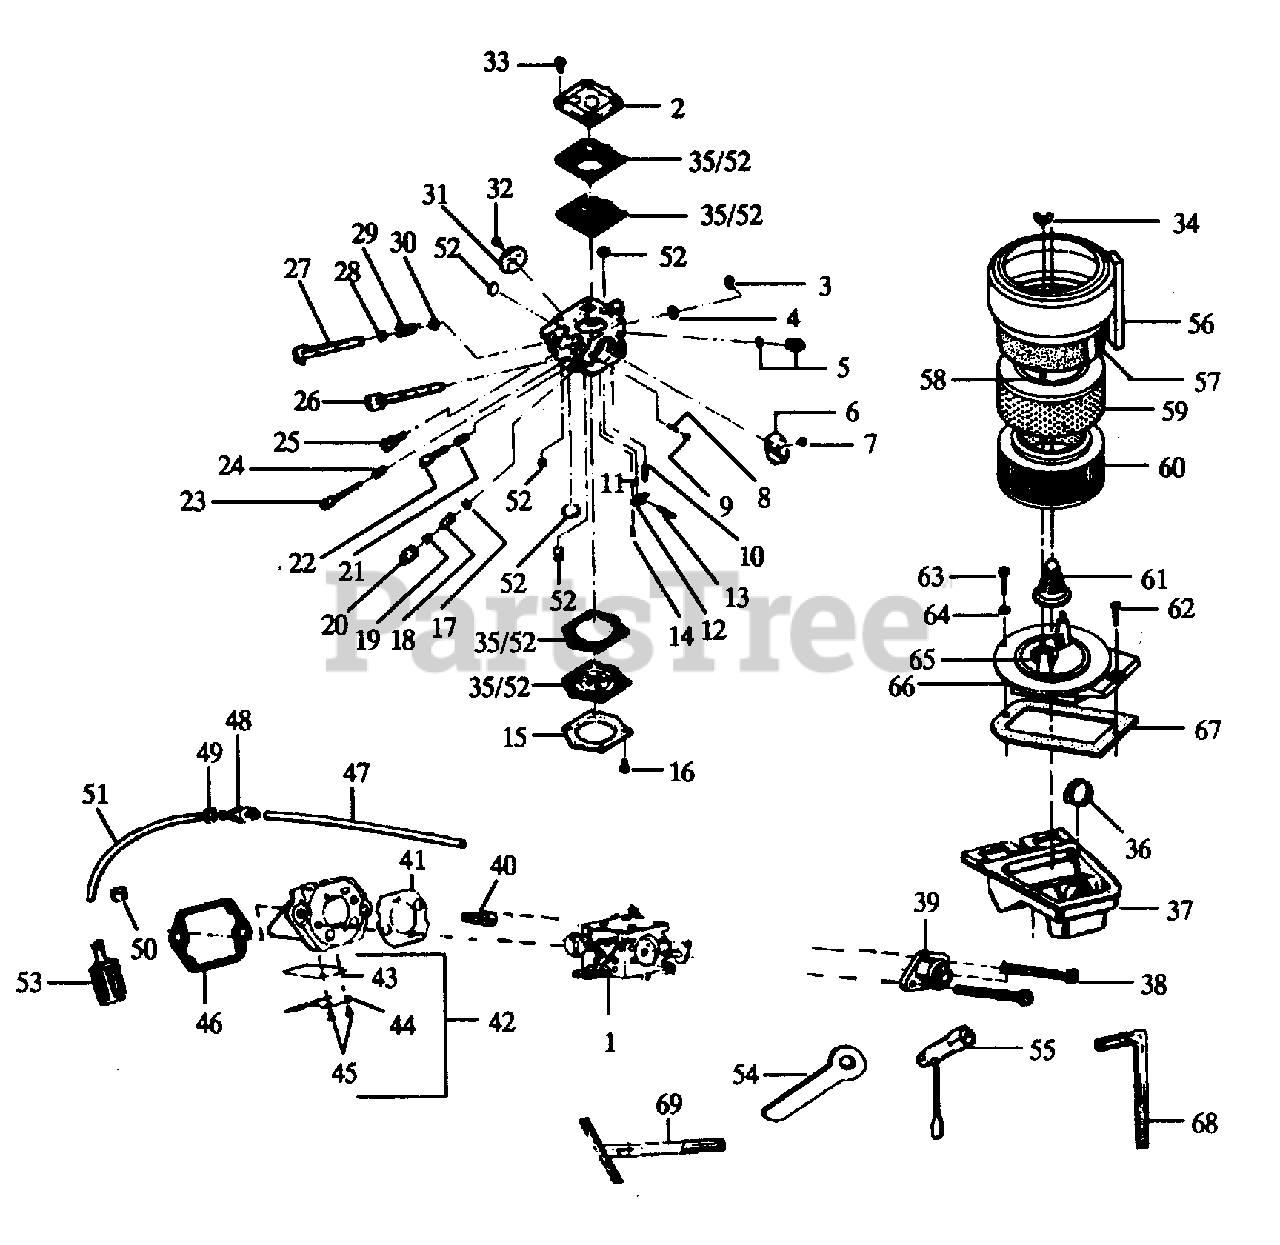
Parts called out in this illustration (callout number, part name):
1	Carburetor WJ-21B
2	Fuel Pump Cover
5	Governor Ass'y.
6	Choke Shutter
10	Valve. Repair Kit.
11	Spring. Repair Kit.
12	Lever. Repair Kit.
13	Metering Lever Pin. Repair Kit.
14	Meter Lever Screw. Repair Kit.
16	Screw
18	Accelerator Pump Diaphragm. Repair Kit/Set of Gaskets.
19	Compression Spring
20	Plug Cover
21	Spring
22	Hi Speed Needle
23	Idle Needle
24	Spring
25	Idle Speed Screw
26	Shaft Ass'y.-Choke
27	Shaft Throttle Ass'y.
29	Throttle Return Spring
31	Throttle Valve
32	Screw-Valve
33	Screw-Cover
34	Wing Nut
35	Gasket & Diaphragm Kit
36	Clamp-Air Box Boot
37	Air Box Boot
39	Blow Back Tube
41	Gasket Reed Body/ Carburetor
42	Reed Valve Ass'y.
43	Reed Valve
44	Back Plate Reed
47	Fuel Hose
48	Fuel Tank Connector
49	Fitting Gasket
50	Speed Clip-Fuel Hose
51	Fuel Hose
52	Carburetor Repair Kit
53	Fuel Filter Ass'y.
55	Combination T Wrench
57	Outer Filter
59	Element Cover
60	Air Filter Element
61	Filter Cone
66	Filter Base
68	Allen Wrench
